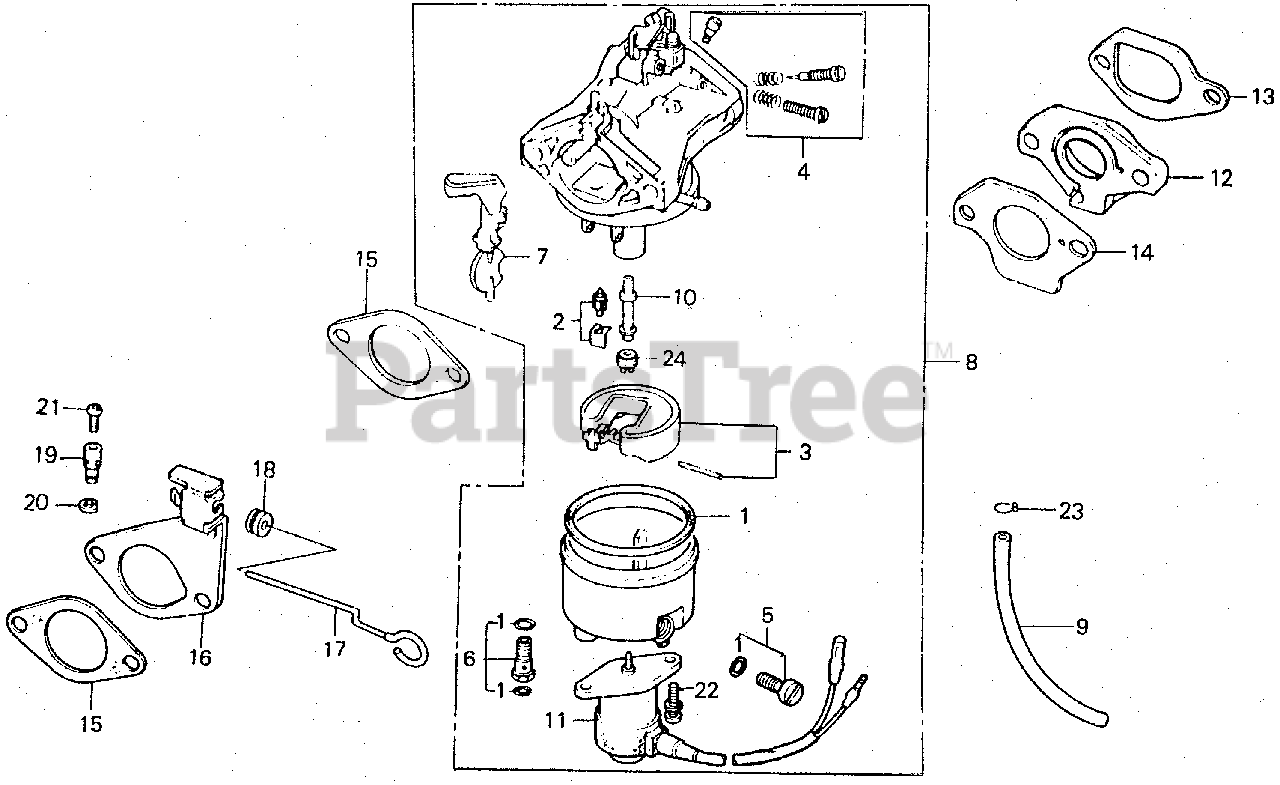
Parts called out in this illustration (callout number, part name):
1	GASKET SET
2	VALVE SET, FLOAT
4	SCREW SET A
4	SCREW SET A (NOT AVAILABLE)
5	SCREW SET, DRAIN
6	SCREW SET B
6	SCREW SET B (NOT AVAILABLE)
8	CARBURETOR ASSY. (BB36A A) (NOT AVAILABLE)
8	CARBURETOR ASSY. (BB36A B) (NOT AVAILABLE)
8	CARBURETOR ASSY.
9	TUBE, DRAIN
10	NOZZLE, MAIN (NOT AVAILABLE)
10	NOZZLE, MAIN
11	VALVE ASSY., SOLENOID (NOT AVAILABLE)
11	VALVE ASSY., SOLENOID
12	INSULATOR, CARBURETOR
13	GASKET, INSULATOR
14	GASKET, CARBURETOR
15	GASKET, AIR CLEANER
16	STAY, CHOKE CONTROL
17	ROD, CHOKE CONTROL
18	GROMMET, CHOKE ROD
19	HOLDER, CABLE
20	CIRCLIP (5MM)
21	SCREW, PAN (4X8)
22	SCREW-WASHER (5X12)
23	CLIP, TUBE (C9)
24	JET, MAIN (#92)
24	JET, MAIN (#92) Use from Engine SN BB36B A.
24	JET, MAIN (#102)
24	JET, MAIN (#85)
24	JET, MAIN (#88)
24	JET, MAIN (#90)
24	JET, MAIN (#95)
